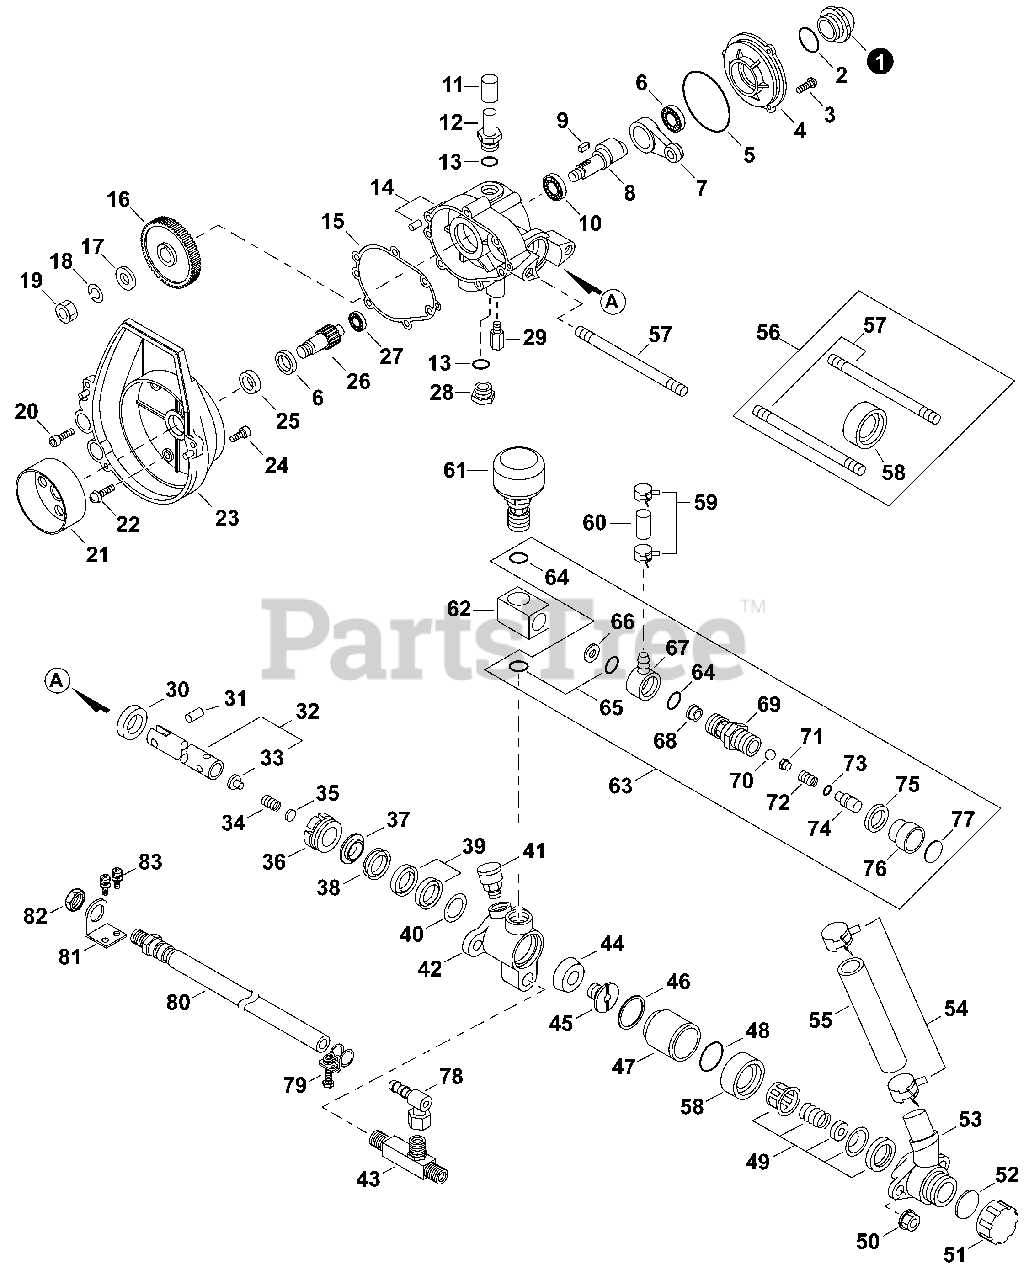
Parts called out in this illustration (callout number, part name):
1	GAUGE, OIL
3	SCREW 4x12
4	COVER, PUMP
6	BEARING, BALL 6001
7	ROD, CONNECTING
8	CRANKSHAFT
10	BEARING, BALL 6201
12	BOLT, OIL
14	CASE KIT, PUMP
15	GASKET, PUMP
16	GEAR, SPUR
17	WASHER 8.5x16x1.2
18	WASHER, SPRING 8
20	BOLT 5x25
21	DRUM, CLUTCH
22	SCREW 5x25
23	COVER, FAN
24	BOLT 5x18
25	SEAL, OIL
26	SHAFT, PINION
27	BEARING, BALL 609
28	CAP, DRAIN
30	SEAL, OIL
31	PIN, PISTON
32	PLUNGER SET, W/SPRING HOLDER
33	HOLDER, SPRING
34	SPRING, VALVE
38	PACKING, GREASE
39	PACKING SET
41	CUP ASSY, GREASE
42	CYLINDER
43	CONNECTOR, HOSE
44	PACKING, PISTON
45	SEAT, VALVE
49	VALVE ASSY
51	CAP, DRAIN
52	GASKET, DRAIN
53	PIPE, INTAKE
55	HOSE, INLET
56	CASING SET, VALVE
57	BOLT, STUD
58	CASING, VALVE
59	CLIP 10.5 MM
60	HOSE, RETURN
61	CHAMBER, AIR
62	CONNECTOR
63	REGULATOR ASSY
64	O-RING 12.5
65	O-RING 16 MM
67	CASING, VALVE
68	SEAT, VALVE
69	CASING, SPRING
70	BALL, PRESSURE STEEL
71	HOLDER, SPRING
72	SPRING, PRESSURE
73	O-RING 7 MM
74	SHAFT, REGULATOR
75	NUT, LOCK
76	CAP, REGULATOR
77	LABEL - REGULATOR
78	JOINT, HOSE
79	BAND, SPRING
80	HOSE, SHORT
81	BRACKET, MOUNTING
82	NUT
83	SCREW 5x14
